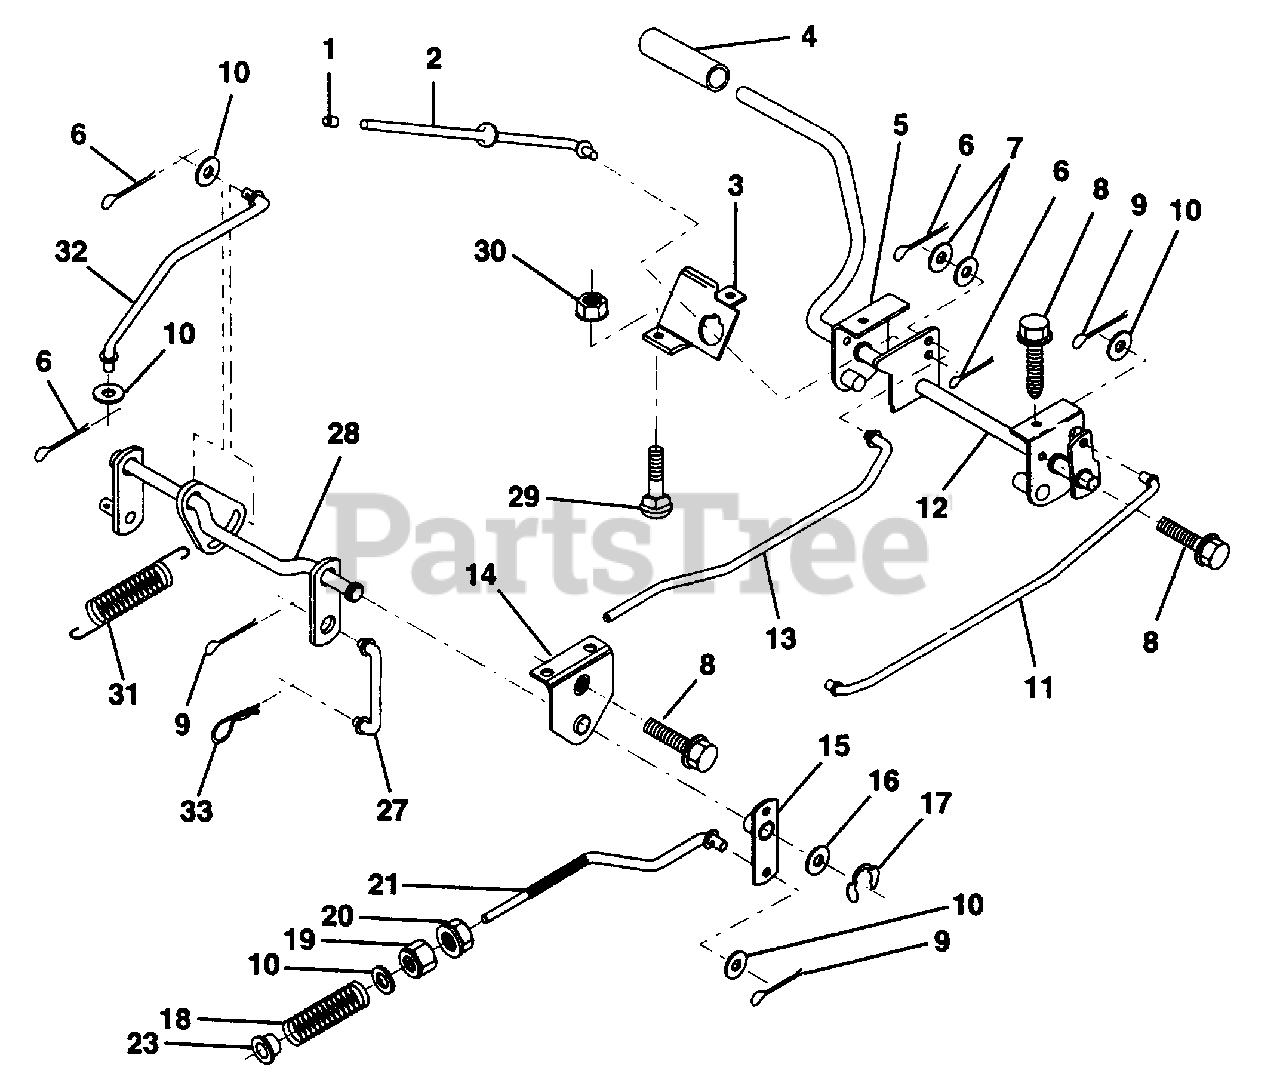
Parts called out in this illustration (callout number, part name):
2	Rod, Parking Brake
3	Bracket, Parking Brake
5	Bracket, Clutch/Brake Pedal, L.H.
6	Pin, Cotter 3/32 x 3/4
7	Washer 13/32 x 5/8 x 16 Gauge
8	Screw, Hex Head, Thd., Roll. 5/16-18 x 1/2
9	Pin, Cotter 1/8 x 3/4
10	Washer 13/32 x 13/16 x 16 Gauge
11	Rod, Brake, Front
12	Assembly, Clutch/Brake Pedal
13	Rod, Clutch
14	Bracket, Lift Shaft
15	Assembly, Brake, Pivot, Arm
16	Washer 25/32 x 1-1/8 x 16 Gauge
18	Spring, Brake Rod
19	Nut, Hex, Jam 3/8-16 UNC
20	Locknut, Hex, w/Wsh Ins 3/8-16 UNC
21	Rod, Brake, Rear
23	Bushing, Link Drag Blk
27	Link, Lift, Rear
28	Assembly, Rear Mower Lift
29	Bolt, Carriage 5/16-18 UNC x 3/4
30	Nut, Hex, Keps 5/16-16 UNC
31	Spring, Counterbalance
32	Link, Lift Lever
33	Retainer Spring
